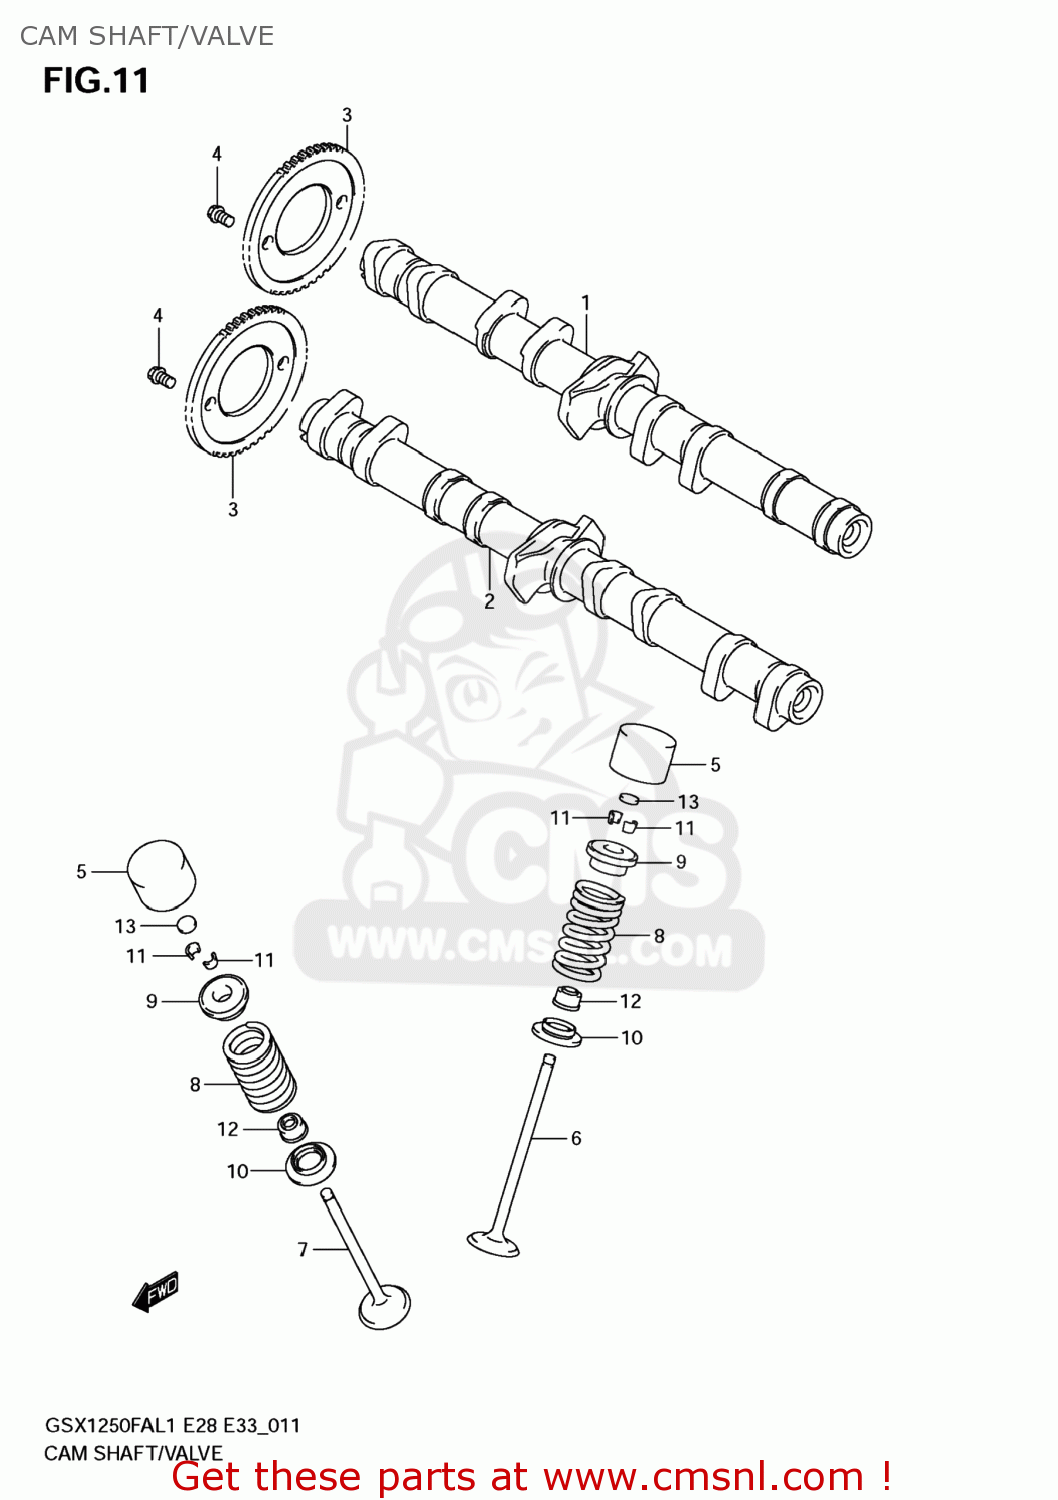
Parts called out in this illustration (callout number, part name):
1	CAMSHAFT,INTAKE
2	CAMSHAFT,EXHAUST
3	SPROCKET,CAMSHAFT
4	BOLT(7X11)
5	TAPPET
6	VALVE,INTAKE
7	VALVE,EXHAUST
8	SPRING,VALVE
9	RETAINER,VALVE SPRING
10	SEAT,VALVE SPRING
11	COTTER VALVE
12	SEAL,OIL(4.5X10X8)
13	SHIM,TAPPET
14	SHIM SET,TAPPET
15	CASE,TAPPET SHIM
